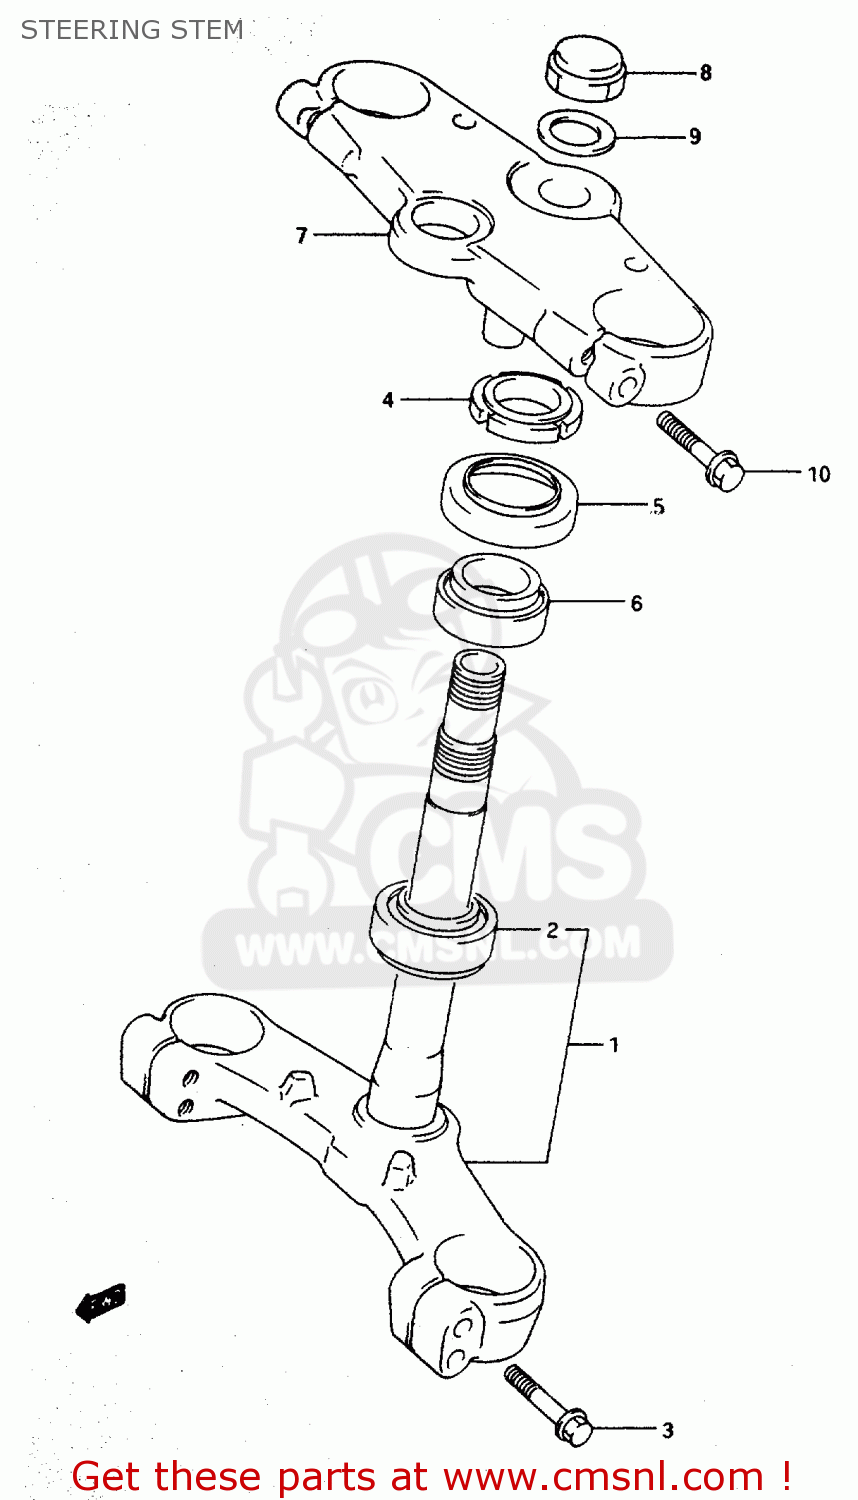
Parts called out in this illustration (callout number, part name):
1	STEM,STEERING
2	BEARING(30X55X17)
3	BOLT
4	NUT,STEERING STEM(25X44X10)
5	SEAL,STEERING UPR DUST
6	BEARING(25X47X15)
7	HEAD,STEERING STEM
8	NUT,CAP
9	WASHER(22.5X32X1.6)
10	BOLT
